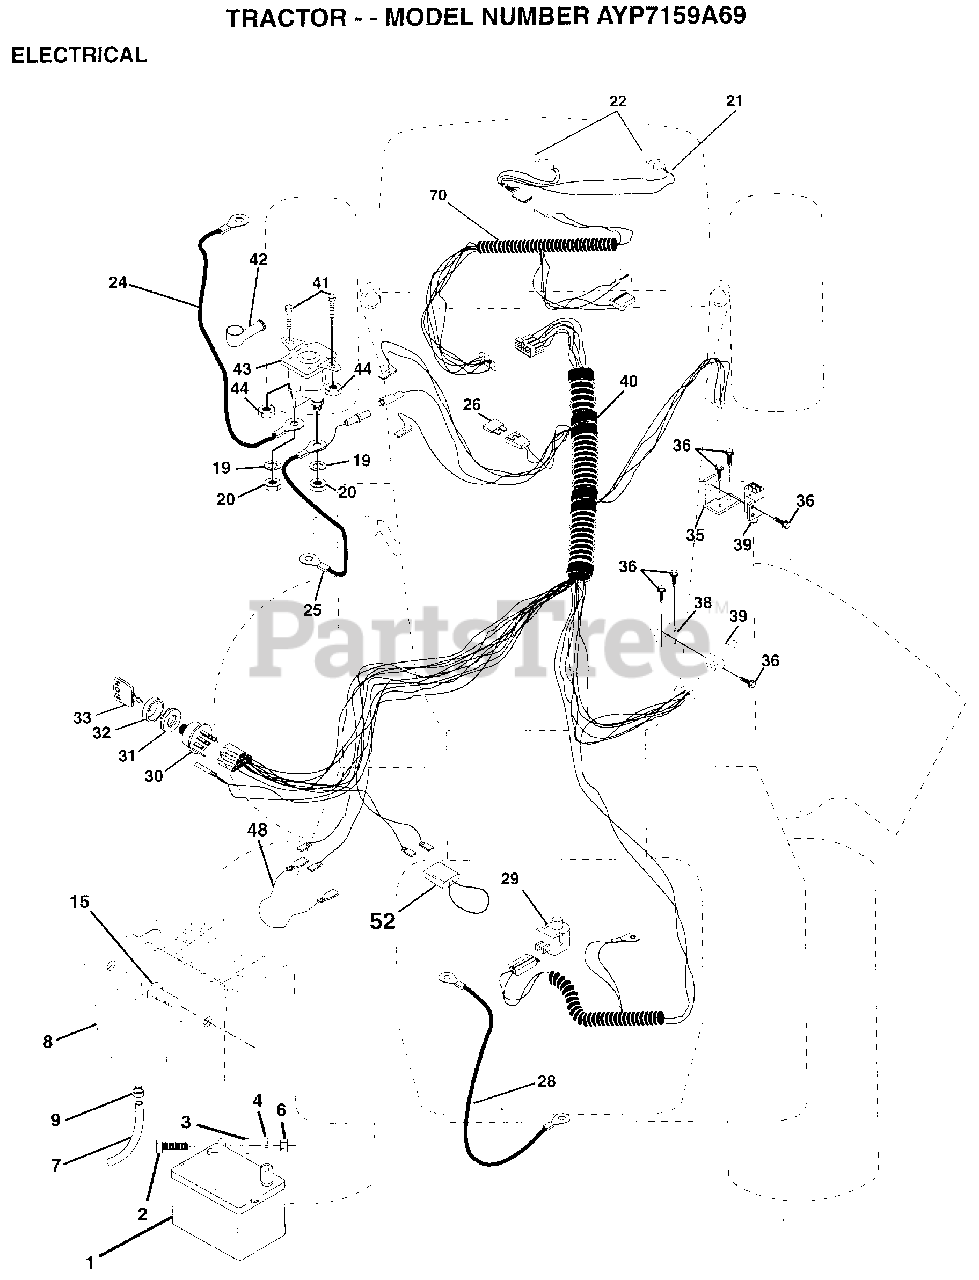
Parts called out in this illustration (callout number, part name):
2	BOLT LT
3	WASHER
4	LOCKWASHER
7	TUBE T
9	HOSE CLAMP T
15	FASTNER.SNAP-IN
20	NUT
21	"HARNESS,LIGHT SOC"
22	HEADLAMP BULB
24	"CABLE T, BATTERY"
25	CABLE.BTRY.6GA.RD
26	FUSE HYT
28	CABLE T
29	SWITCH SEAT
30	SWITCH IGN 4POS
31	NUT IGNITION
32	COVER KEY SWITCH
33	KEY
35	BRACKET LT
36	SCREW
38	BRACKET SWITCH IN
39	SWITCH INTERLOCKT
40	HARNESS.IGNITION
41	BOLT HXHD FIN
44	NUT HXKEP 1/4X20
46	PROTECTION LOOP
70	HARNESS ENGINE
